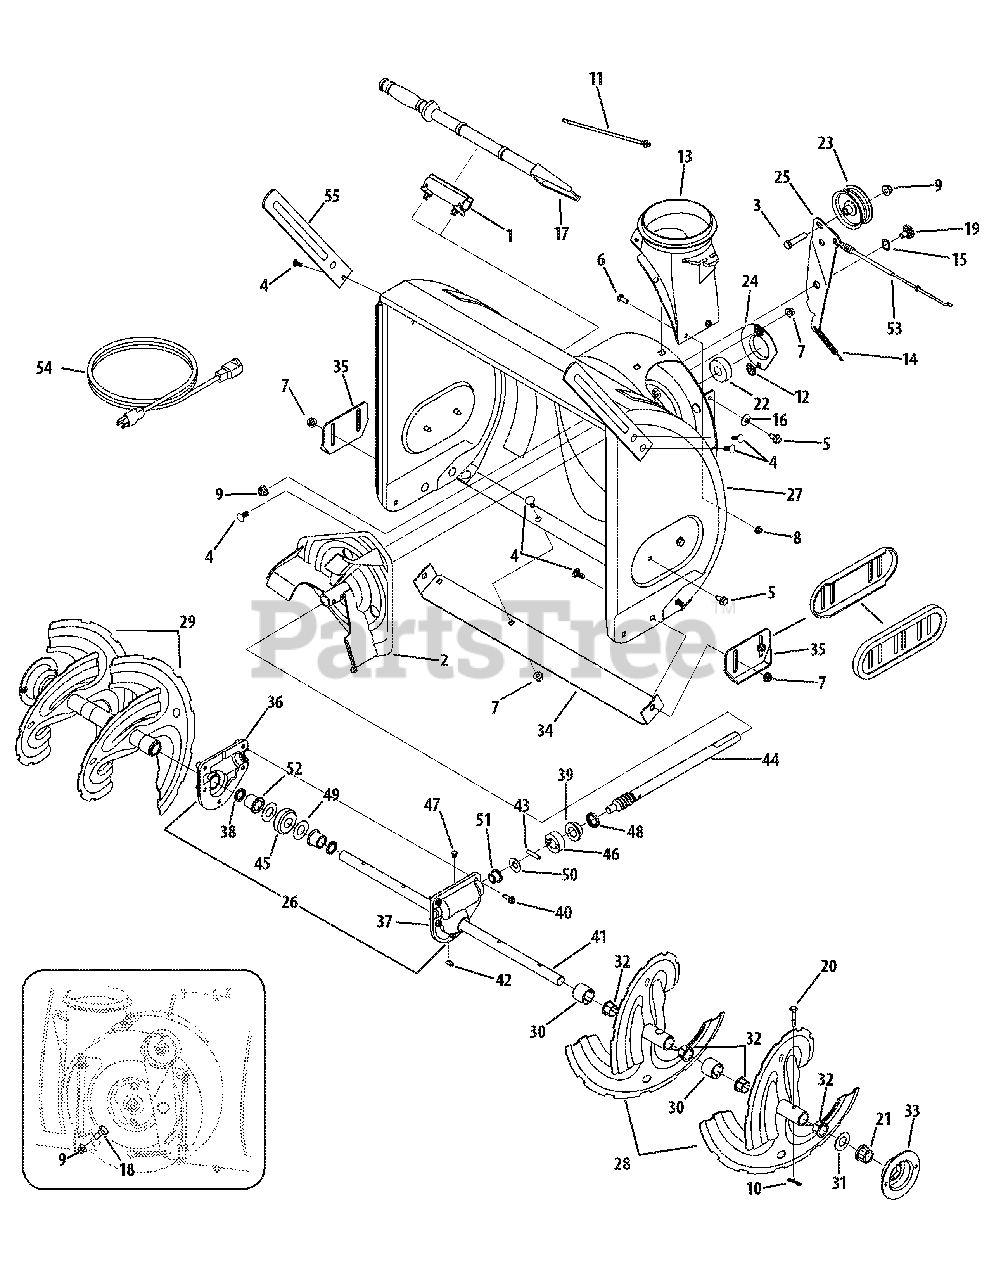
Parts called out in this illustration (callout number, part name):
1	Snow Removal Tool Mount
3	Hex, Screw,3/8-16, 1.75
4	Carriage Bolt, 5/16-18, .750
5	Screw, 5/16-18, 0.750
6	Carriage Screw, 1/4-20, .750
7	Flange Lock Nut, 5/16-18, Nylon
8	Flange Lock Nut, 1/4-20, Nylon
9	Flange Lock Nut,3/8-16, Nylon
10	Bow-Tie Cotter Pin
11	Cable Tie, 3/16 x .05 x 7.4
12	Push-On Nut, .25
13	Chute Adapter, 5''
14	Extension Spring, .38 OD x 4.59
15	Wave Washer, .625 x .885 x .015
16	Bell Washer, .340 x .872 x .060
17	Snow Removal Tool
18	Shoulder Screw, .498 x .34, 3/8-16
19	Shoulder Screw, .625 x .17, 3/8-16
20	Shear Pin, .25 x 1.50
21	Hex Flange Bearing
22	Ball Bearing, .75 ID x 1.85 OD
23	Idler Flat Pulley, 2.75 OD
24	Bearing Housing, 1.85 ID
26	Auger Gearbox Assembly, 22''
26	Auger Gearbox Assembly, 24''
26	Auger Gearbox Assembly, 26''
26	Auger Gearbox Assembly, 28''
26	Auger Gearbox Assembly, 30''
30	Spacer, 1.25 OD x .75 ID x 1.00
31	Flat Washer, .76 x 1.49 x .06
32	Flange Bushing, .80 ID x .91 OD
35	Skid Shoe, Plastic
35	Skid Shoe, Stainless
36	Auger Housing, RH Reduced
37	Auger Housing, LH Reduced
38	Oil Seal, .75 x 1.131 x 1.88
39	Flange Bearing, .75 x 1.0 x .59
40	Self-tapping Screw, 1/4-20, 0.750
41	Auger Axle, 22''
41	Auger Axle, 24''
41	Auger Axle, 26''
41	Auger Axle, 28''
41	Auger Axle, 30''
42	Hi-Pro Key, 3/16 x 5/8
43	Dowel Pin, .25 OD x 1.2
44	Worm Shaft, .75 OD
45	Worm Gear, 20T
46	Thurst Collar
47	Plug, 1/4 x .437
48	Oil Seal, .75 x 1 x.131
49	Flat Washer, .760 ID x 1.5 OD
50	Flat Washer, .51 x 1.12
51	Flange Bearing, .75 x 1.0 x .925
52	Flange Bearing, .75 x 1.00 x .59
53	Auger Clutch Cable, 47.23''
54	Extension Cord, 110V, 3-prong
